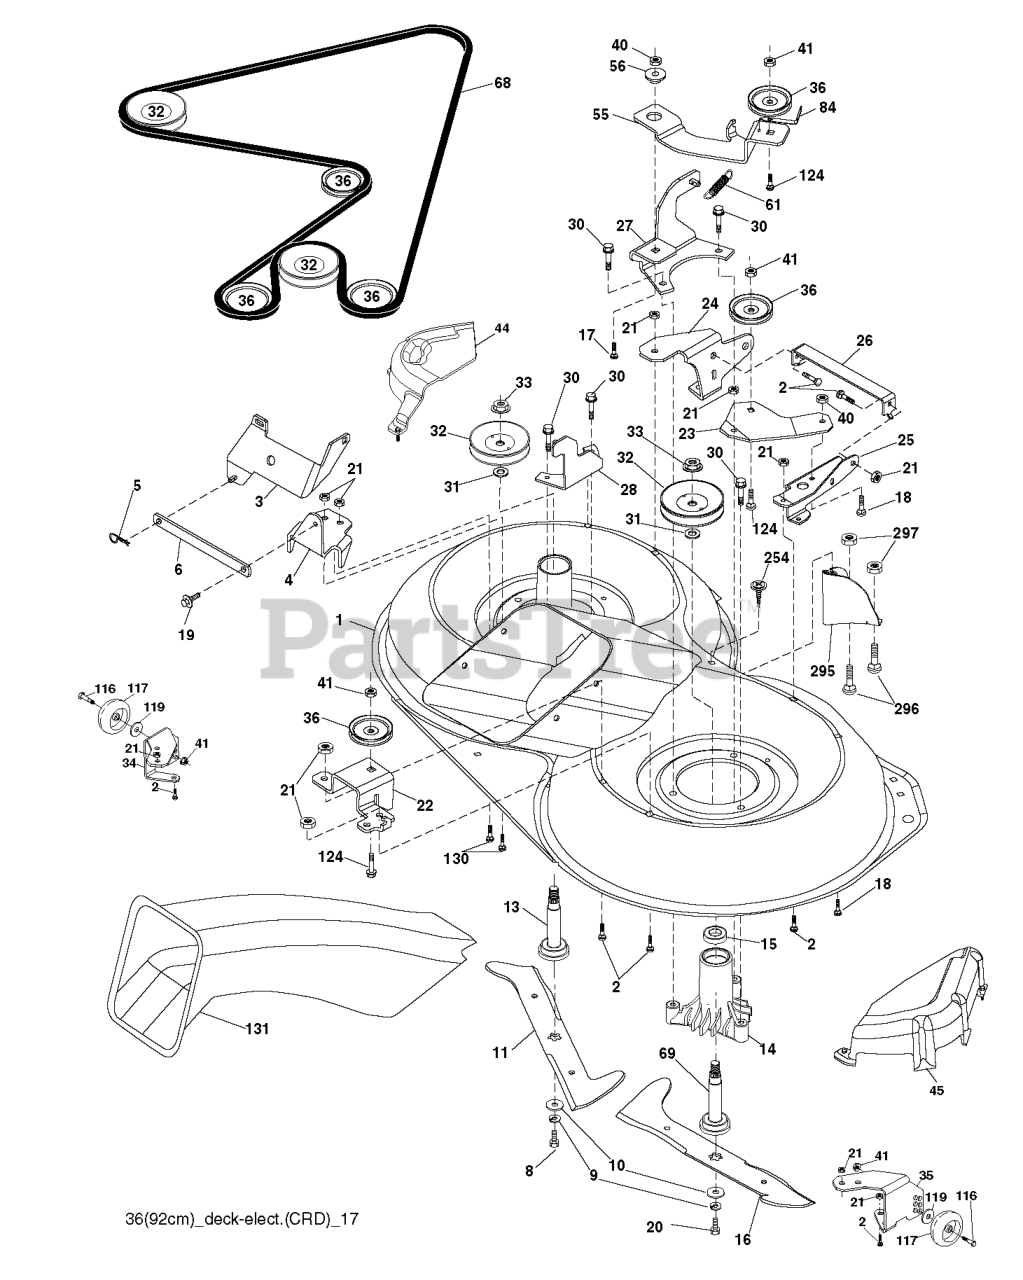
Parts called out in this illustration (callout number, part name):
2	RP BOLT 5/16-18 X3/4 ZN/YEL GR
5	RETAINER-SPRNG RB
6	BAR.SWAY.92.CRD
8	BOLT.3/8-24X1.25 GR8
9	LOCKWASHER
10	WASHER.BLADE
13	SHAFT ASM VENT
14	HOUSING.MANDREL.VENTED (MACHD)
17	BOLT.3/8-14X1.25
19	BOLT SHD 5/16-18
20	BOLT.3/8-24X1.25GR8. LHTHRD
21	LOCKNUT
26	SUPPORT
30	SCREW, WASHER HEAD
31	WASHER.SPACER.MANDREL
32	PULLEY MANDREL
33	NUT.FLANGE.LOCK.TOP
36	PULLEY.IDLER.4.25
41	NUT LOCK FLG 3/8-16 UNC
45	COVER.MANDREL.RH.CRD
46	SCREW.1/4-20X5/8
55	ARM.IDLER.92 CRD.2006
56	SPACER.RETAINER.MOWER
61	SPRING
68	BELT.DRIVE.92CM.CRD.2006
69	SHAFT.ASM.W/LWR.BRG.RH.THREAD
84	KEEPER, BELT IDLER
116	BOLT.SHOULDER.3/8-16X3-5/8.
117	RP WHEEL. GUAGE RALLY
119	WASHER
124	BOLT.3/8-16X1.50
130	BOLT.CARR.SQNK.5/16-18UNC.X3/4
131	CHUTE BAGGER
254	SCREW 3/8-16X1
296	BOLT
297	NUT CENTERLOCK
